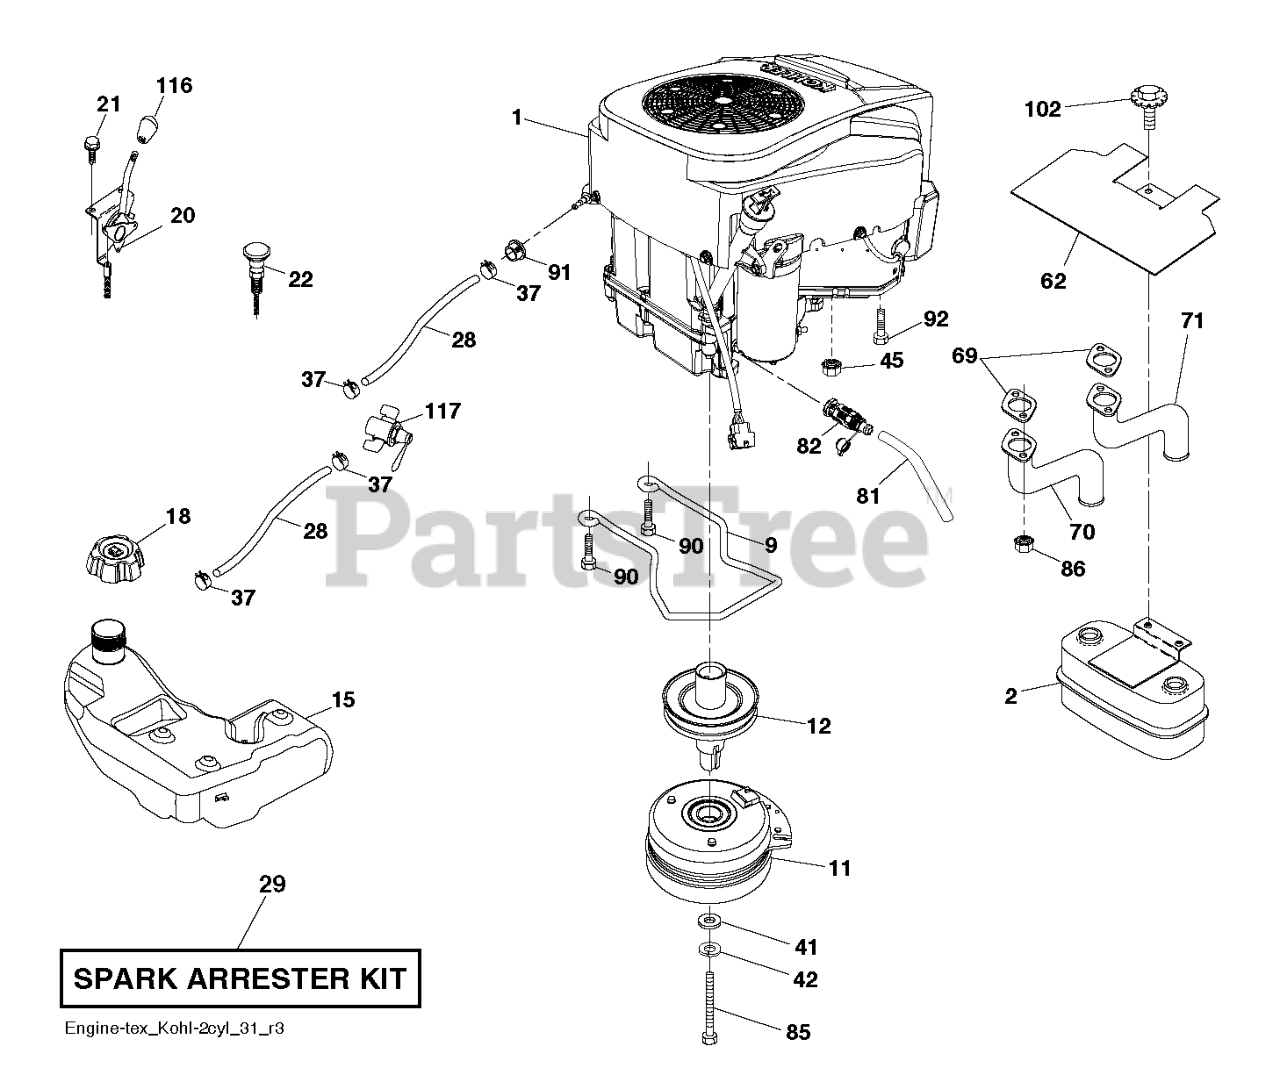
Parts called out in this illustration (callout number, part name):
2	MUFFLER.ASM.TWIN.MNTG.BRACKET
9	KEEPER.BELT.ENG.4.25"2.BLT.431
11	CLUTCH. 5.0 PD. 2.5 OFFSET
12	PULLEY.EXTENDED.SHAFT.GROUND
18	CAP ASSY FUEL 3" BLACK
20	THROTTLE.KOHL.PRO.#88PAD_46"
21	SCREW.#10X.750
22	CONTROL.CHOKE.ERGO.PUSH-IN.BLA
28	HOSE 1/4" LOW PERMEATION FUEL
29	KIT.SPARK ARRESTOR 794945 B&S
37	HOSE CLAMP
42	WASHER 7/16 LOCK
45	NUT
62	SHIELD.HEAT.MUFFLER
69	GASKET.EXHAUST.KOHL.CV18-CV26
70	PIPE.EXHAUST.LH.CV18/20
71	PIPE.EXHAUST.RH.CV18/20
81	TUBE, DRAIN OIL ASM.
82	VALUE.OIL.DRAIN
85	BOLT.HEX.7/16-20X5.GR5.GREEN
86	NUT.HEX.FLANGE.TOPLOCK
90	SCREW 3/8-16X1
91	BUSHING.1.375OD
92	SCREW 3/8-16X1
102	SCREW
116	KNOB - SHIFT
117	VALVE FUEL RESERVE
